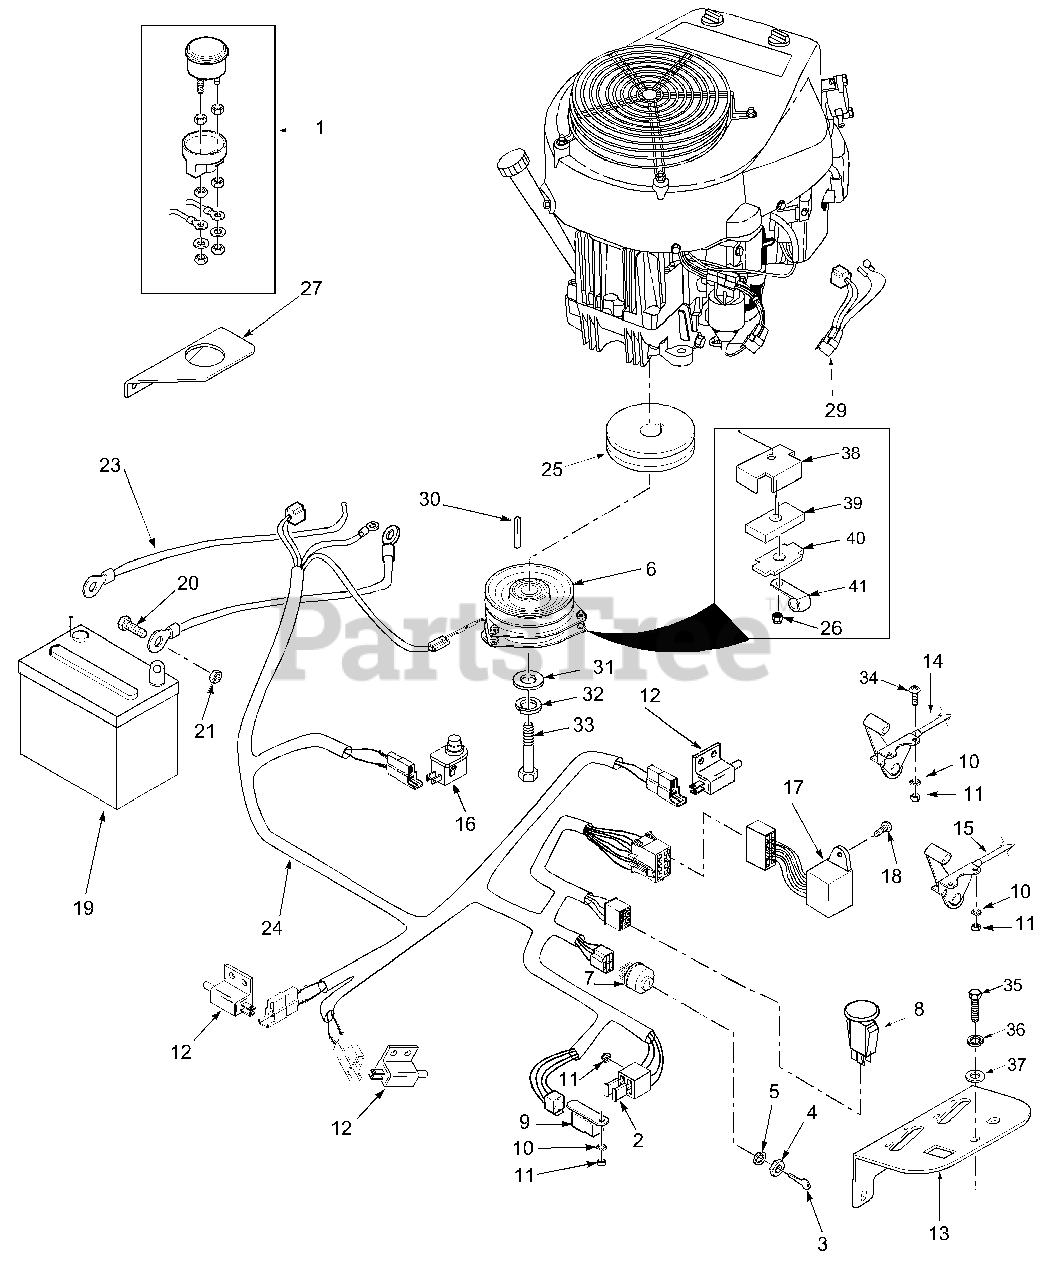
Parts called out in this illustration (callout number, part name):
1	Hourmeter
2	Fuse, 20 amp
3	Key, Ignition
4	Nut, Hex 5/8-32
5	Lockwasher, 5/8" Internal
6	Electric PTO Clutch
7	Switch, Ignition
8	Switch, PTO
9	Relay
10	Lock Washer, #10 External Tooth
11	Nut, Hex #10-32
12	Switch, N/O
13	Panel, Instrument
14	Choke & Throttle Control - Kawasaki
15	Throttle Control - Kohler
16	Switch, Seat
17	Module, Interlock
18	Screw, #10-32 x .5" Phillips Head
19	Battery
20	Bolt, Hex Head 1/4-20 x .5"
21	Nut, Hex 1/4-20
23	Cable, Battery Red (positive)
24	Wiring Harness, Main
25	Pulley, 5.45 OD x 1.125 Bore
26	Nut, Elastic Stop 5/16-18 Key
27	Mounting Bracket, Hour Meter
29	Adaptor, Wiring Harness (Kawasaki only)
30	Key, 1/4 x 1/4 x 3-1/4"
31	Flatwasher, 7/16-.469 x 1-3/4" x 1/4"
32	Lockwasher, 7/16"
33	Bolt, Hex Head 7/16-20 x 2-1/2" UNF
34	Screw, #10-32 x 3/4"
35	Bolt, Hex Head 5/16-18 x 3/4"
36	Lockwasher, 5/16
37	Flatwasher, 5/16-.375 x .875 x .083
38	Backing Plate
39	Rubber Pad, Clutch Stop
40	Plate, Backing
